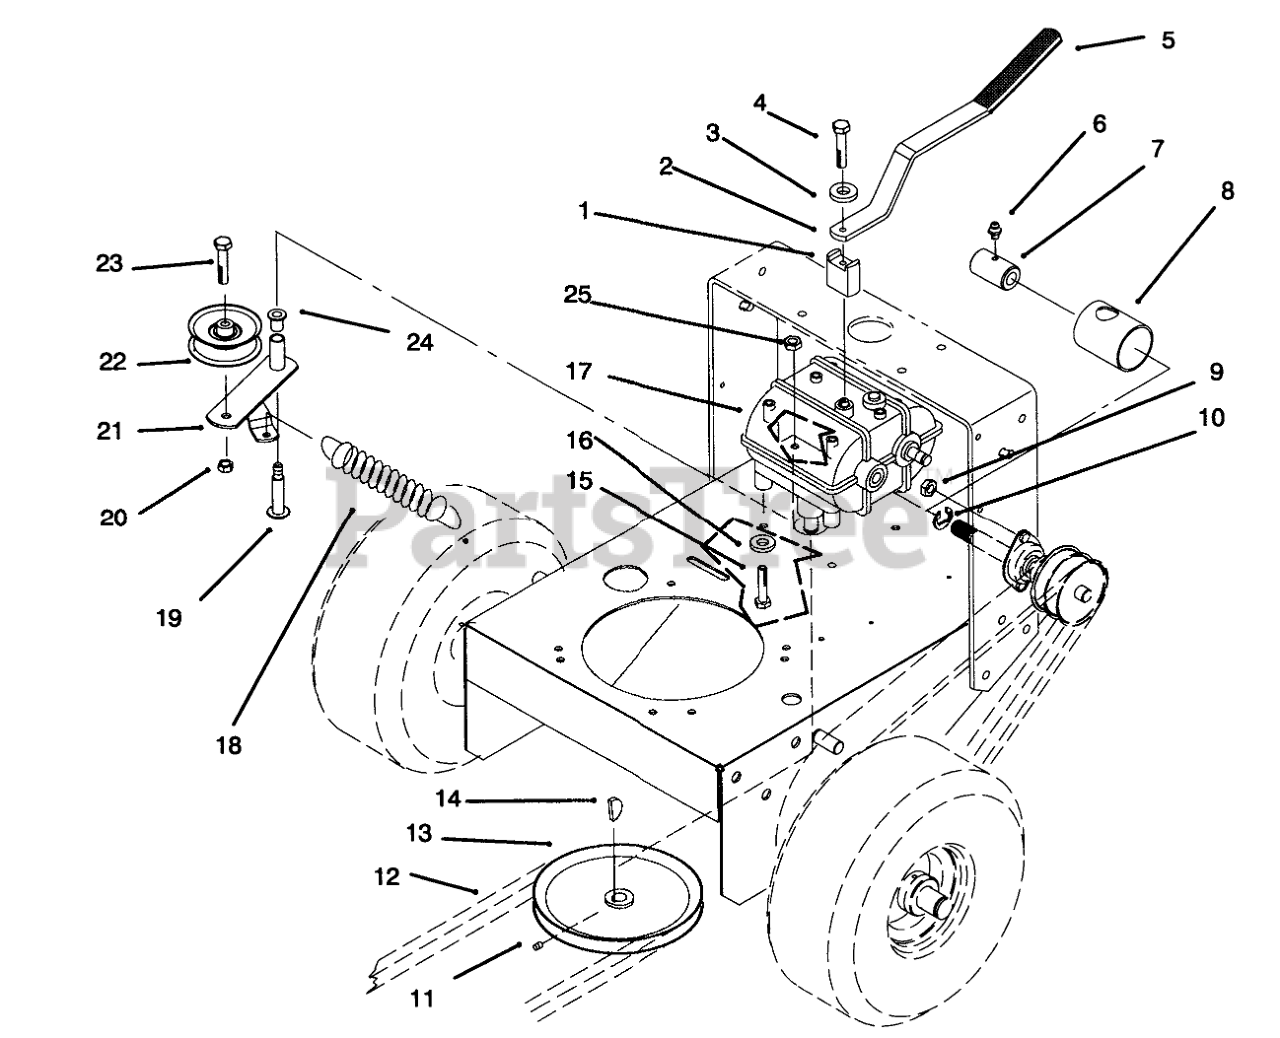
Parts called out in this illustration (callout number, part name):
1	MOUNT-LEVER, SHIFT
2	Lever-Shift
3	SPACER
4	SCREW-HH
6	FITTING-GREASE
7	COUPLER
8	GUARD-COUPLER
9	NUT-LOCK, NI
10	RING-SNAP, EXTERNAL
11	SCREW-SET
12	V-BELT
13	PULLEY-DRIVEN
15	SCREW-HH
16	WASHER-LOCK
17	TRANSMISSION
18	SPRING
19	BOLT-WHEEL
20	NUT-LOCK, NI
21	Lever-Idler (Incl. Ref.#24)
22	PULLEY
23	SCREW-HH
24	BUSHING-FLANGE
25	NUT-LOCK
